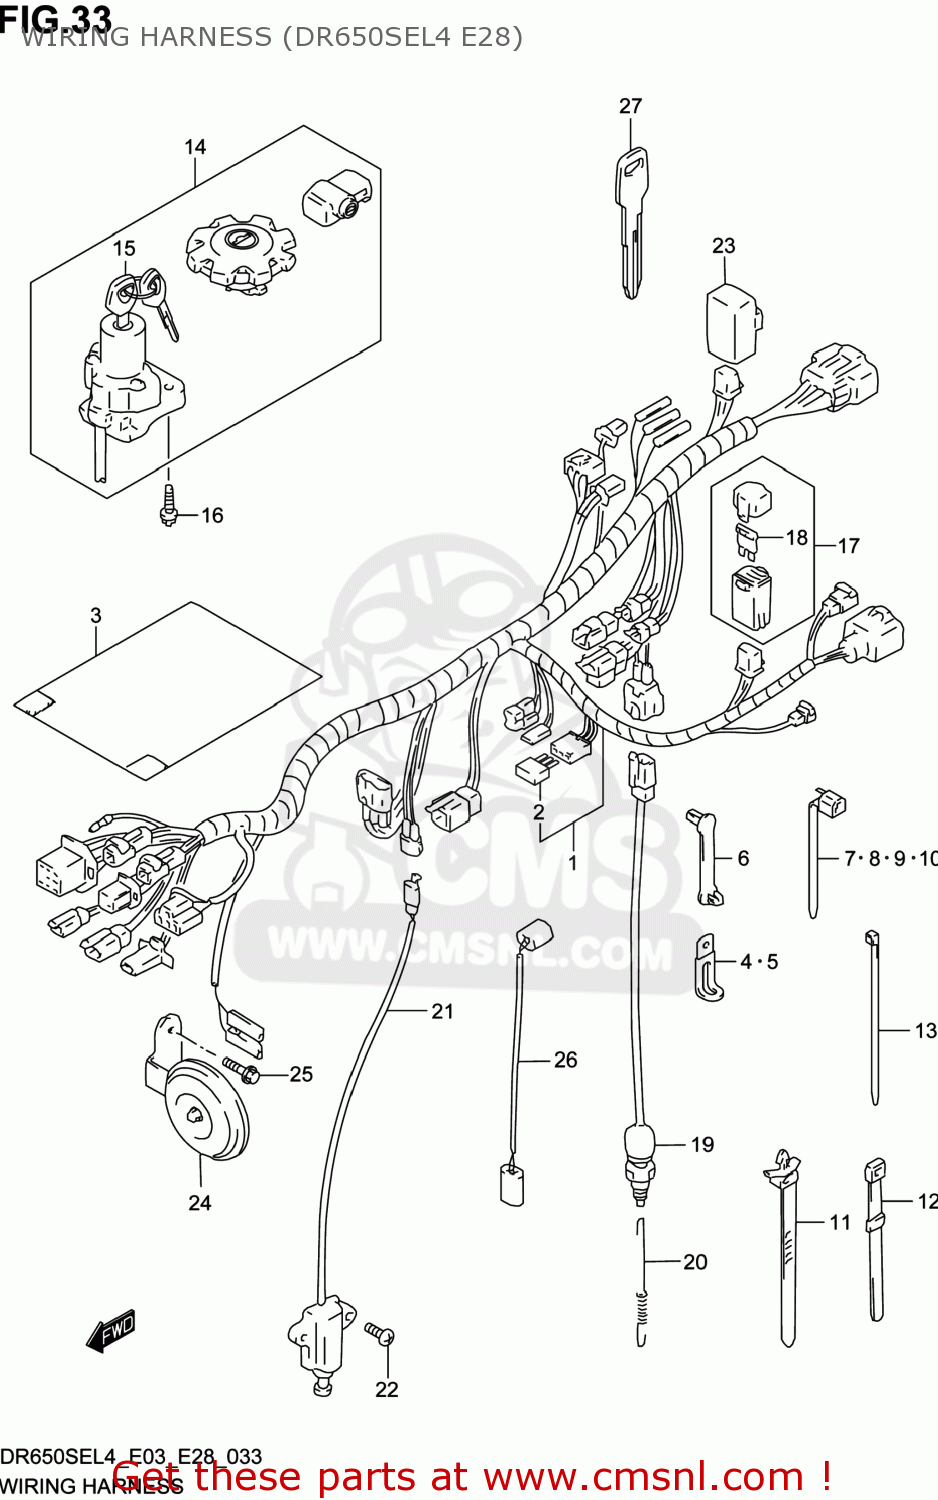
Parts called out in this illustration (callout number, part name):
1	HARNESS,WIRING
2	DIODE(STANLEY DE8804)
3	COVER,WIRING HARNESS
4	CLAMP(L:45)
5	CLAMP(L:80)
6	CLAMP(L:33)
7	CLAMP(L:95)
8	CLAMP(L:125)
9	CLAMP(L:165)
10	CLAMP(L:235)
11	CLAMP(L:90)
12	CLAMP(L:120)
13	CLAMP(L:100)
14	LOCK SET
15	LOCK ASSY,STEERING
16	BOLT(8X20)
17	BOX ASSY,FUSE
18	FUSE(10A)
19	SWITCH ASSY,STOP LAMP
20	SPRING
21	SWITCH ASSY,SIDE STAND
22	SCREW
23	RELAY ASSY
24	HORN ASSY
25	BOLT
26	WIRE,THROTTLE SENSOR
27	KEY,BLANK
